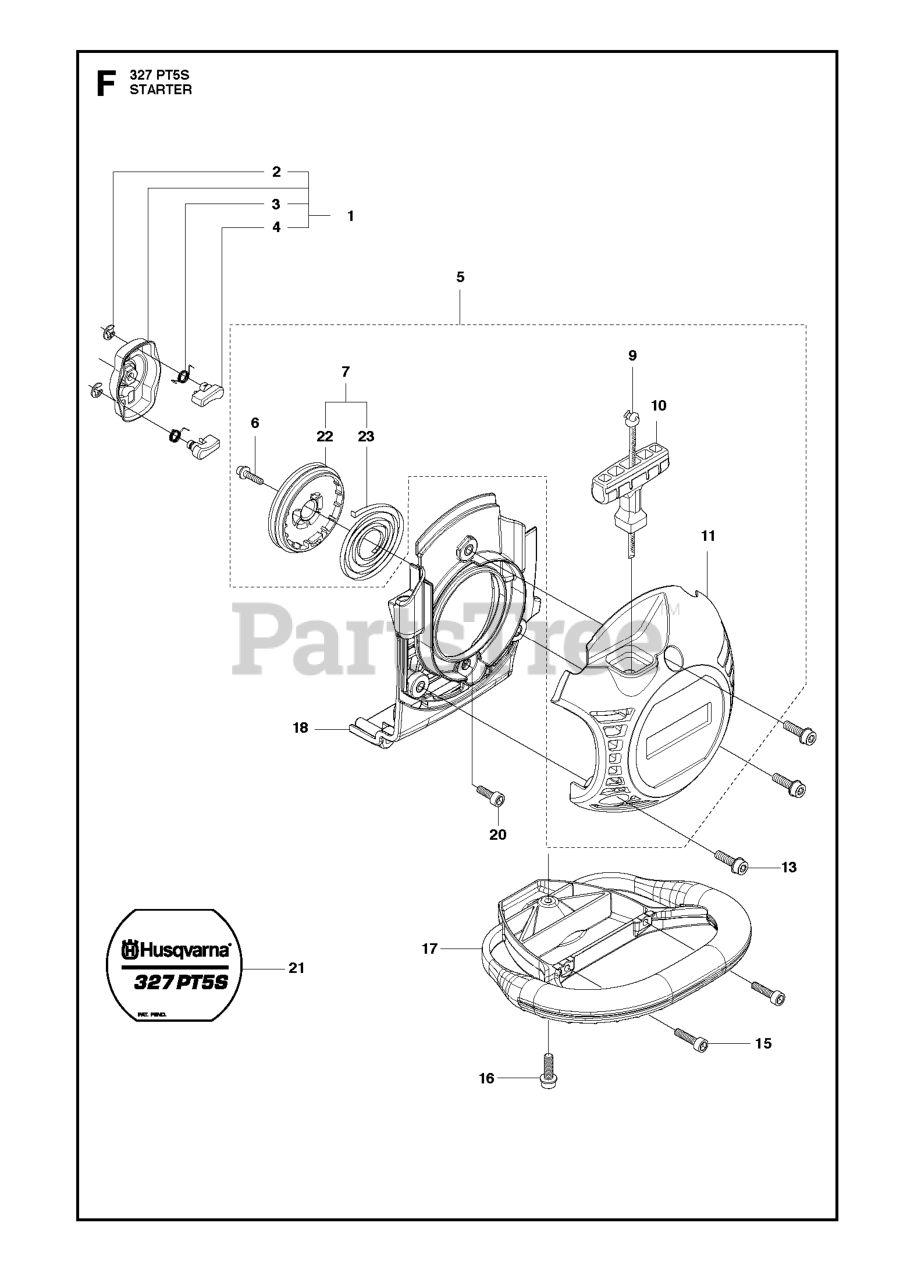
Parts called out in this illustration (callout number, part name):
1	STARTER PAWL BRIDGE
4	STARTER PAWL
5	STARTER ASSY
7	STARTER PULLEY
9	STARTER ROPE
10	STARTER HANDLE
11	STARTER HOUSING
13	SCREW
16	SCREW
18	BRACKET ASSY
23	STARTER SPRING
